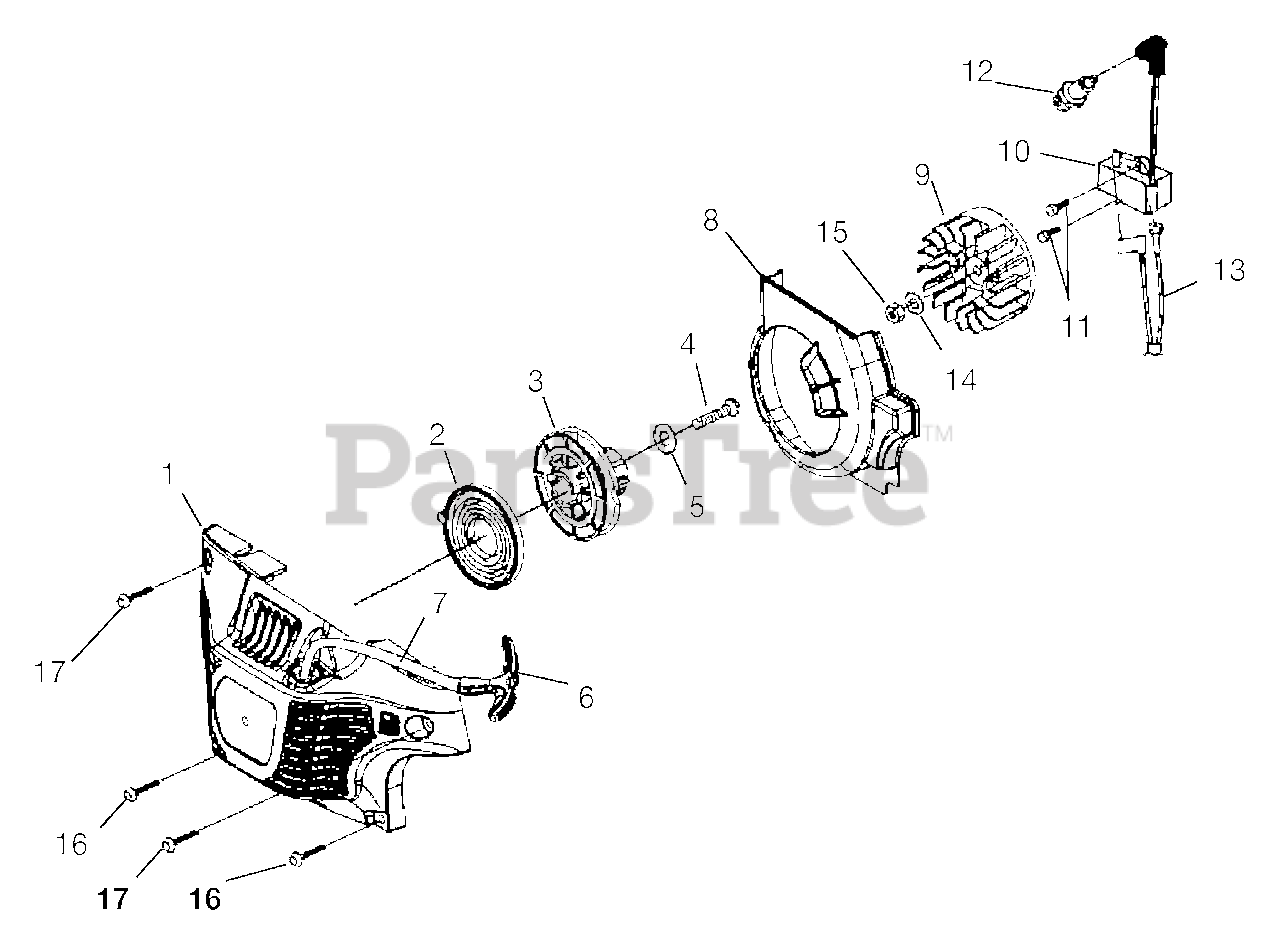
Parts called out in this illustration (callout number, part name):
1	Starter Kit
2	Spring & Container
3	Pulley, Starter
4	Screw, Thread Form (10-14 x 5/8")
5	Washer, Retaining
6	Grip, Starter
7	Rope, Starter 46"
8	Baffle, Fan Housing
9	Rotor w/ Starter Pawl
10	Ignition Kit
11	Screw, Thread Form (8-32 x 5/8")
12	Spark Plug
13	Ignition Switc Harness
14	Washer, Flat
15	Nut, Jam
16	Screw, Truss Hd. (10-14 x 7/8")
17	Screw, Truss Hd. (10-14 x 5/8")
